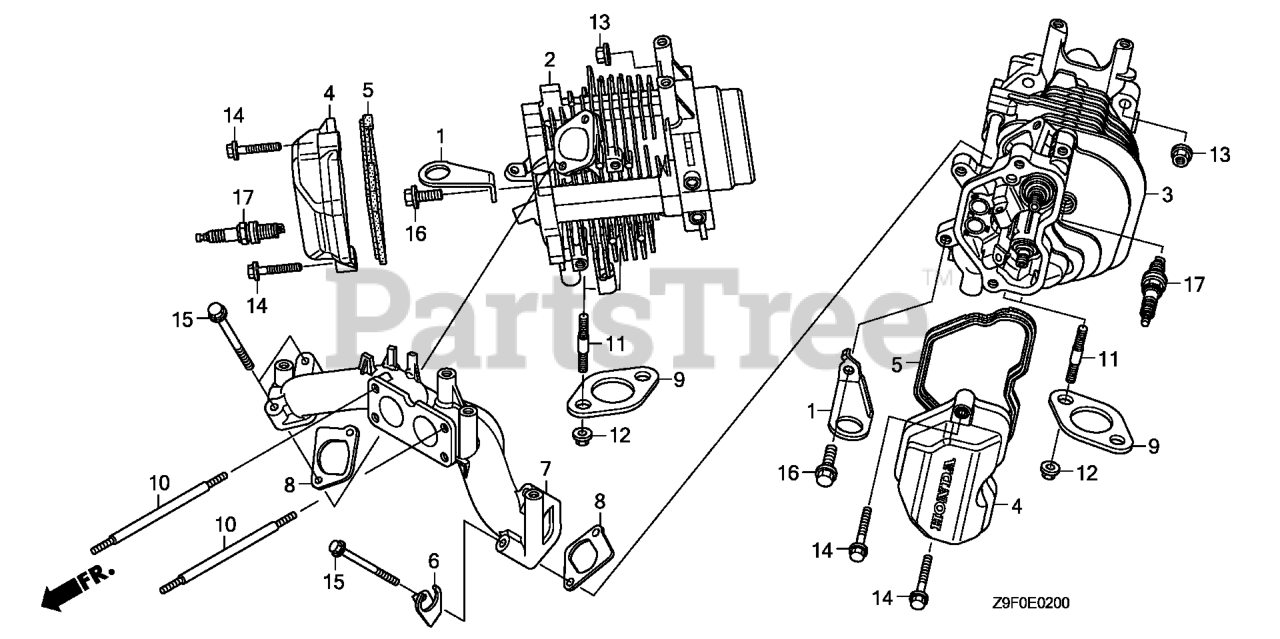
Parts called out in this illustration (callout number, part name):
1	HANGER, ENGINE
2	CYLINDER HEAD (#1)
3	CYLINDER HEAD
3	CYLINDER HEAD (#2)
4	COVER, CYLINDER HEAD
5	GASKET, HEAD COVER
6	STAY, FUEL TUBE GROMMET
7	MANIFOLD, IN.
8	GASKET, IN. MANIFOLD
9	GASKET, EX. PIPE
10	BOLT, STUD (6X100)
11	BOLT, STUD (8X22)
12	NUT, FLANGE (8MM)
13	NUT, FLANGE (10MM)
14	BOLT, FLANGE (6X30)
15	BOLT, FLANGE (6X50)
15	BOLT, FLANGE (8X55)
16	BOLT, FLANGE (8X16) Use from Engine SN 1000016.
17	SPARK PLUG (ZFR5F)
